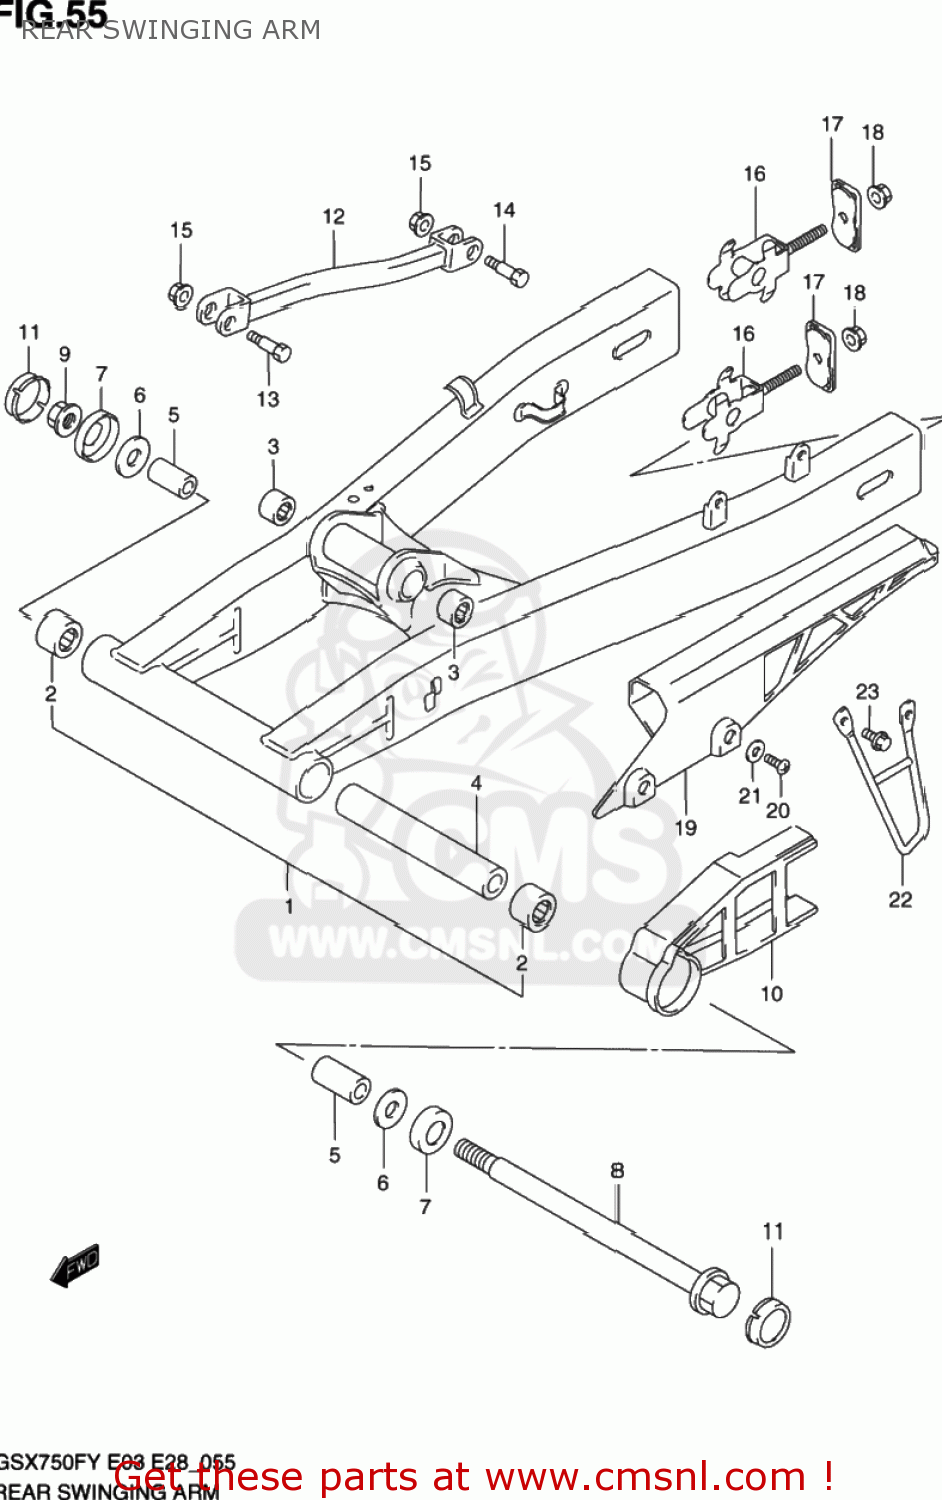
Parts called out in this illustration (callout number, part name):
1	SWINGINGARM ASSY,RR
2	BEARING(22X29X30)
3	BEARING(20X27X23.5)
4	SPACER,RR SWGARM PIVOT CTR
5	SPACER,RR SWGARM PIVOT
6	WASHER
7	COVER,RR SWGARM DUST SEAL
8	SHAFT,RR SWINGINGARM PIVOT
9	NUT
10	BUFFER,CHAIN TOUCH DEFENSE
11	CAP,SWINGINGARM PIVOT
12	TORQUELINK,RR
13	BOLT(10X39)
14	BOLT(10X34)
15	NUT
16	ADJUSTER,CHAIN
17	PLATE,CHAIN ADJ GUIDE
18	NUT
19	CASE,CHAIN
20	SCREW 6X12
21	WASHER
22	GUARD,CHAIN
23	BOLT
